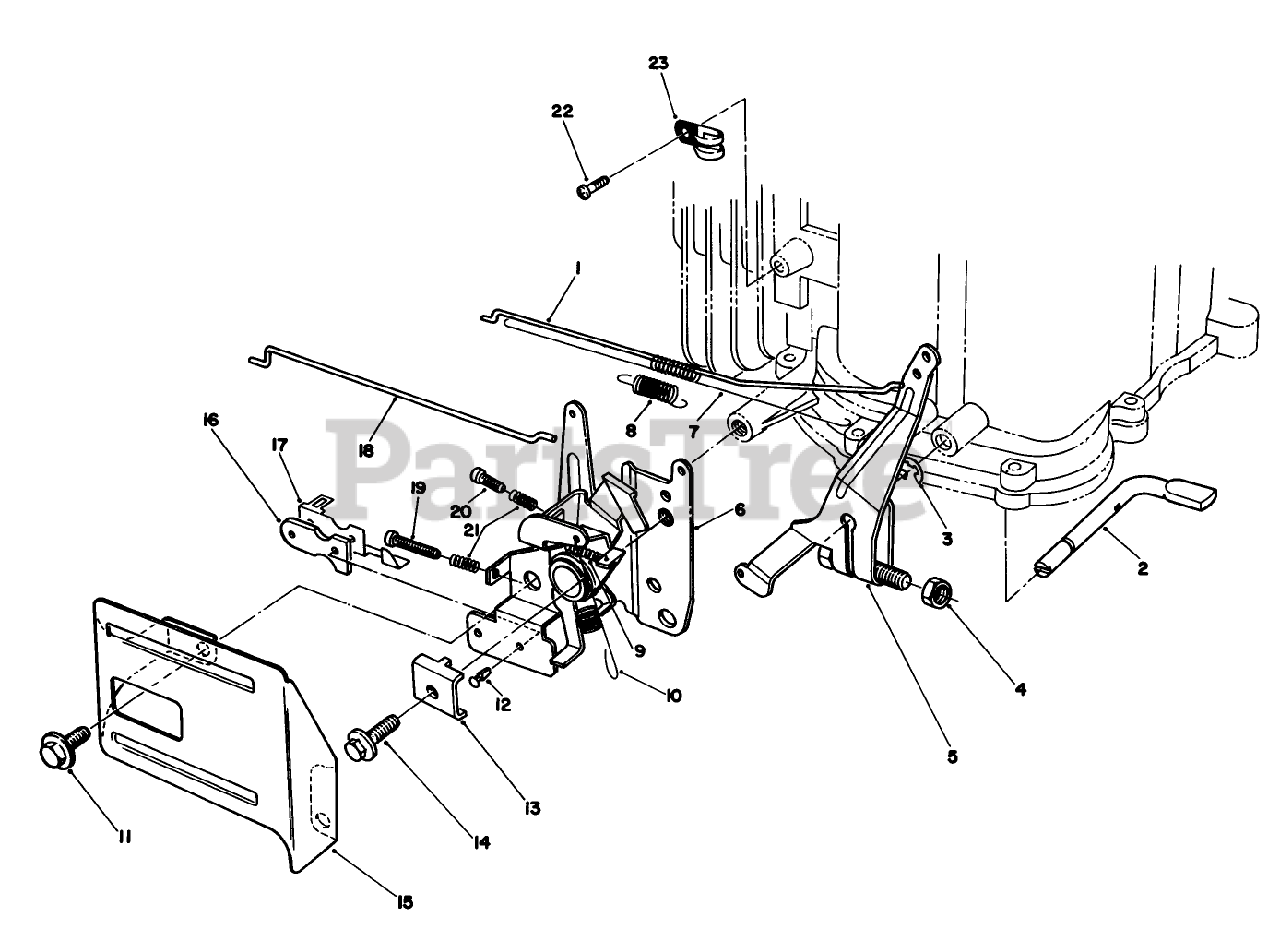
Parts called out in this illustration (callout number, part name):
7	SPRING
8	SPRING
10	SPRING
12	RIVET
13	CLAMP-CABLE
15	THROTTLE GUARD *
16	INSULATOR-KILL SWITCH
17	TERMINAL-KILL SWITCH
21	SPRING
22	SCREW
